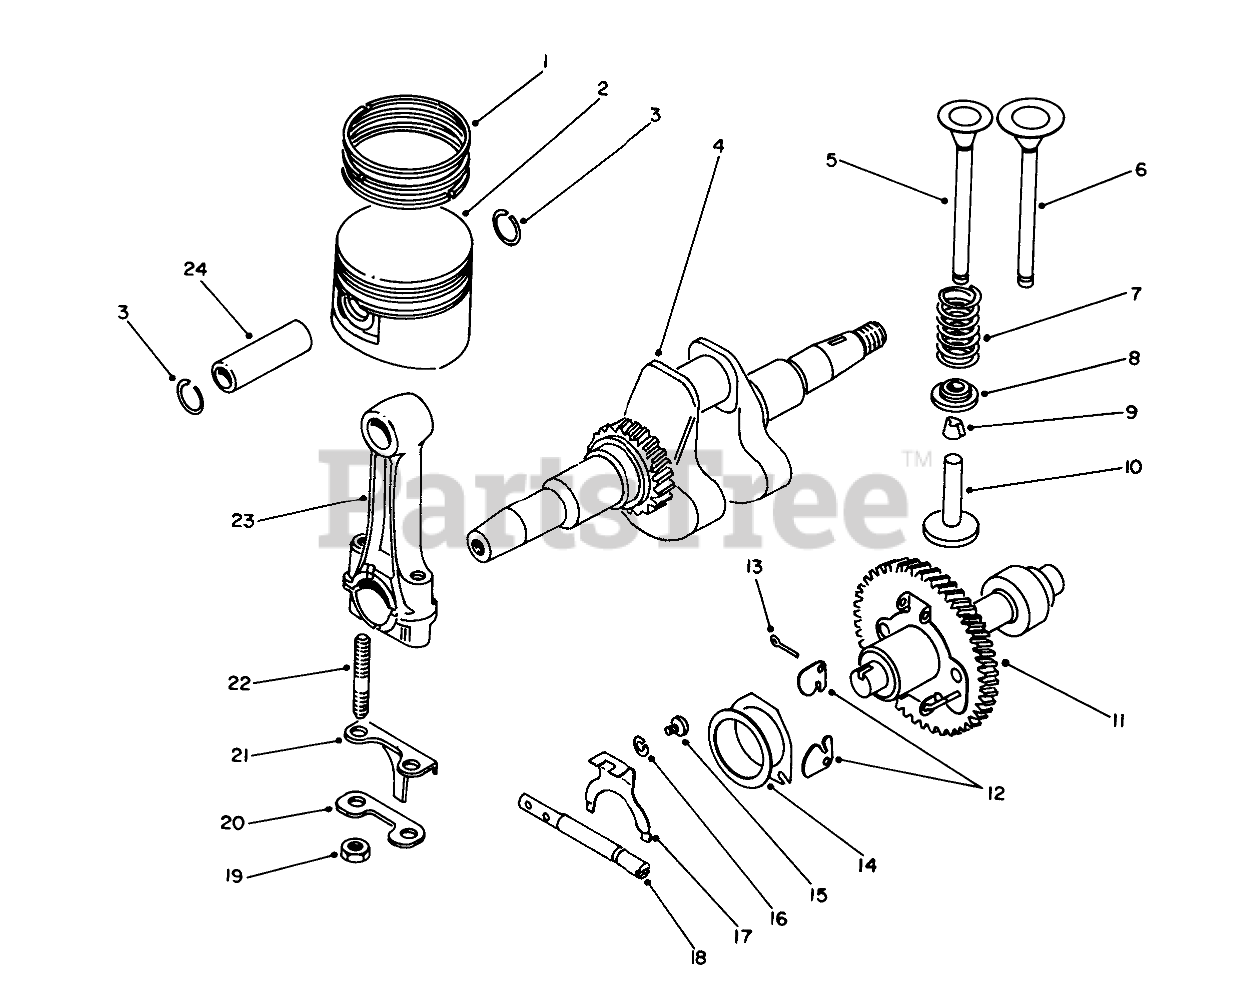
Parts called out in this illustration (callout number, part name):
1	Ring Set-Piston Std.
2	Piston Std.
3	CIRCLIP
4	Bushing
5	Valve-Exhaust
6	Valve-Intake
7	Spring-Valve
8	Retainer
9	Cotter
10	Tappet (L:36.46)
11	Cam Shaft
13	Cotter Pin
14	Spacer
15	SCREW
16	Washer
17	Plate-Shift
18	Shaft-Throttle Return
20	LOCK PLATE
21	PLATE
22	Stud Bolt
23	Rod-Connecting
24	PISTON PIN
